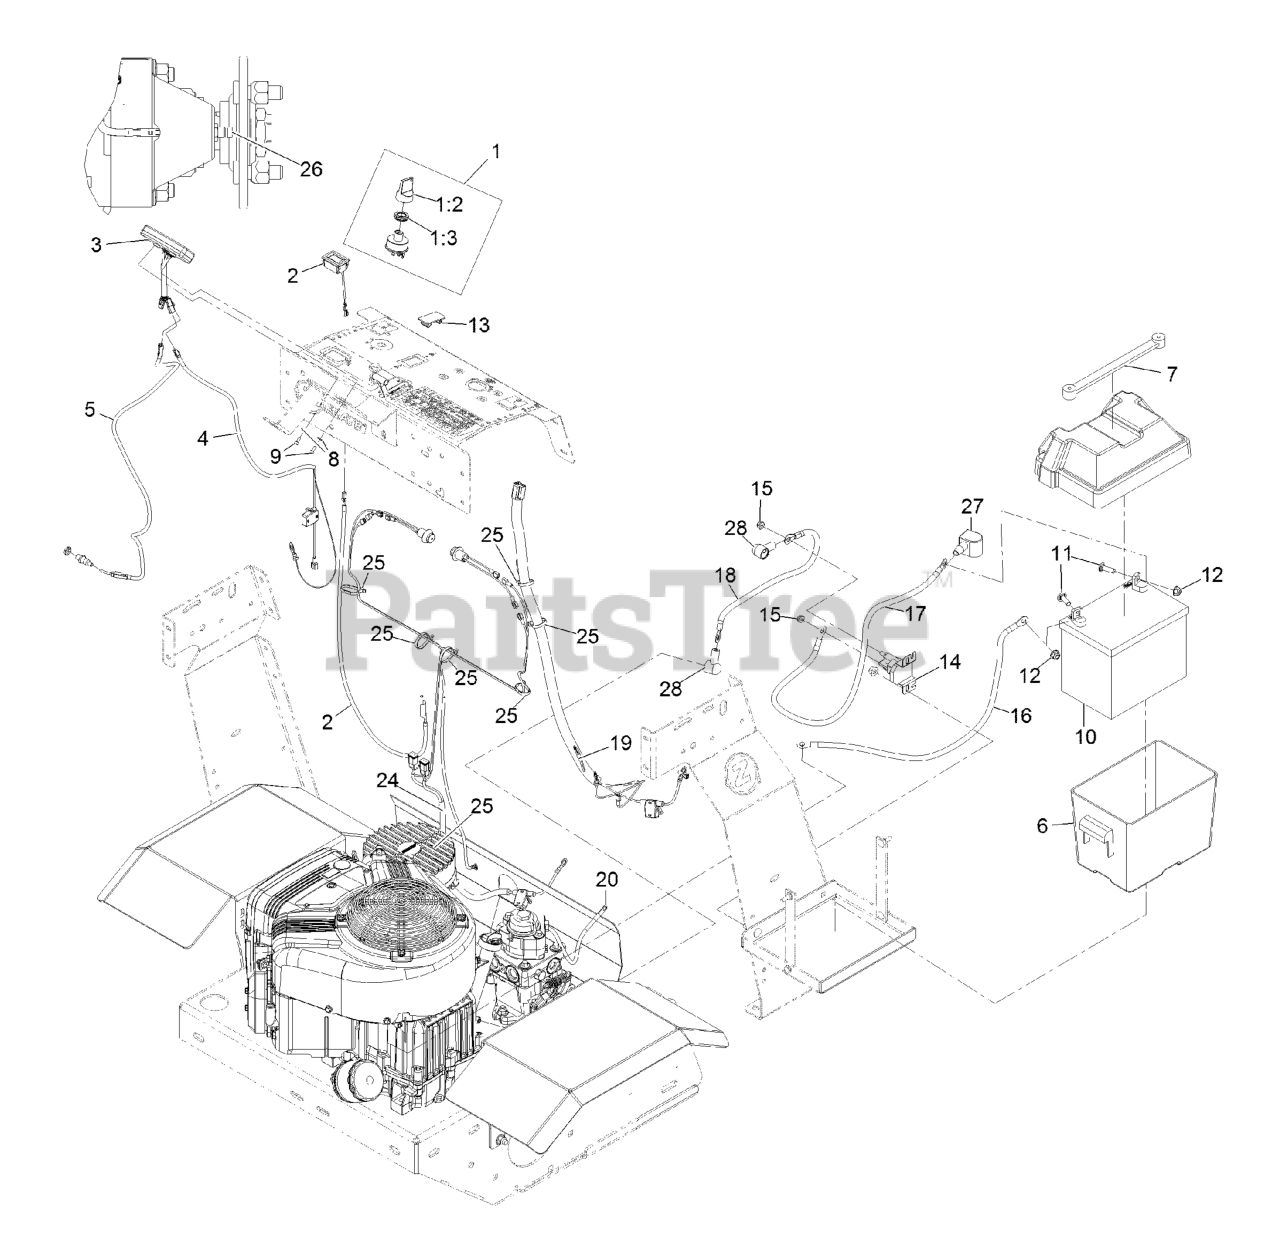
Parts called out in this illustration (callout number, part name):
1	ASM-SWITCH, KEY
1:2	KEY-UMBRELLA
1:3	NUT-SWITCH, KEY
2	METER-TACH/HOUR
3	HEAD ONLY, STRIKER
4	HARNESS-STRIKER
5	Cable-Trail Tech, Sensor
6	BATTERY BOX ASM
7	BUNGEE (TARP STRAP)
8	WASHER-FLAT
9	SCREW-HSH
10	Battery (340 CCA, Wet)
11	SCREW-CARR
12	NUT-HF, NI
13	PLUG-HOLE
14	Solenoid-Starter
16	CABLE-GROUND
17	28" RED BATTERY CABLE
18	CABLE-POSITIVE
19	WIRING HARNESS
20	WIRE-SOLENOID
24	HARNESS, KIT, THUMB SWITCH, ZP
25	TIE-CABLE
26	MAGNET, SPEEDOMETER
27	Insulator-Battery
28	INSULATOR-SOLENOID
